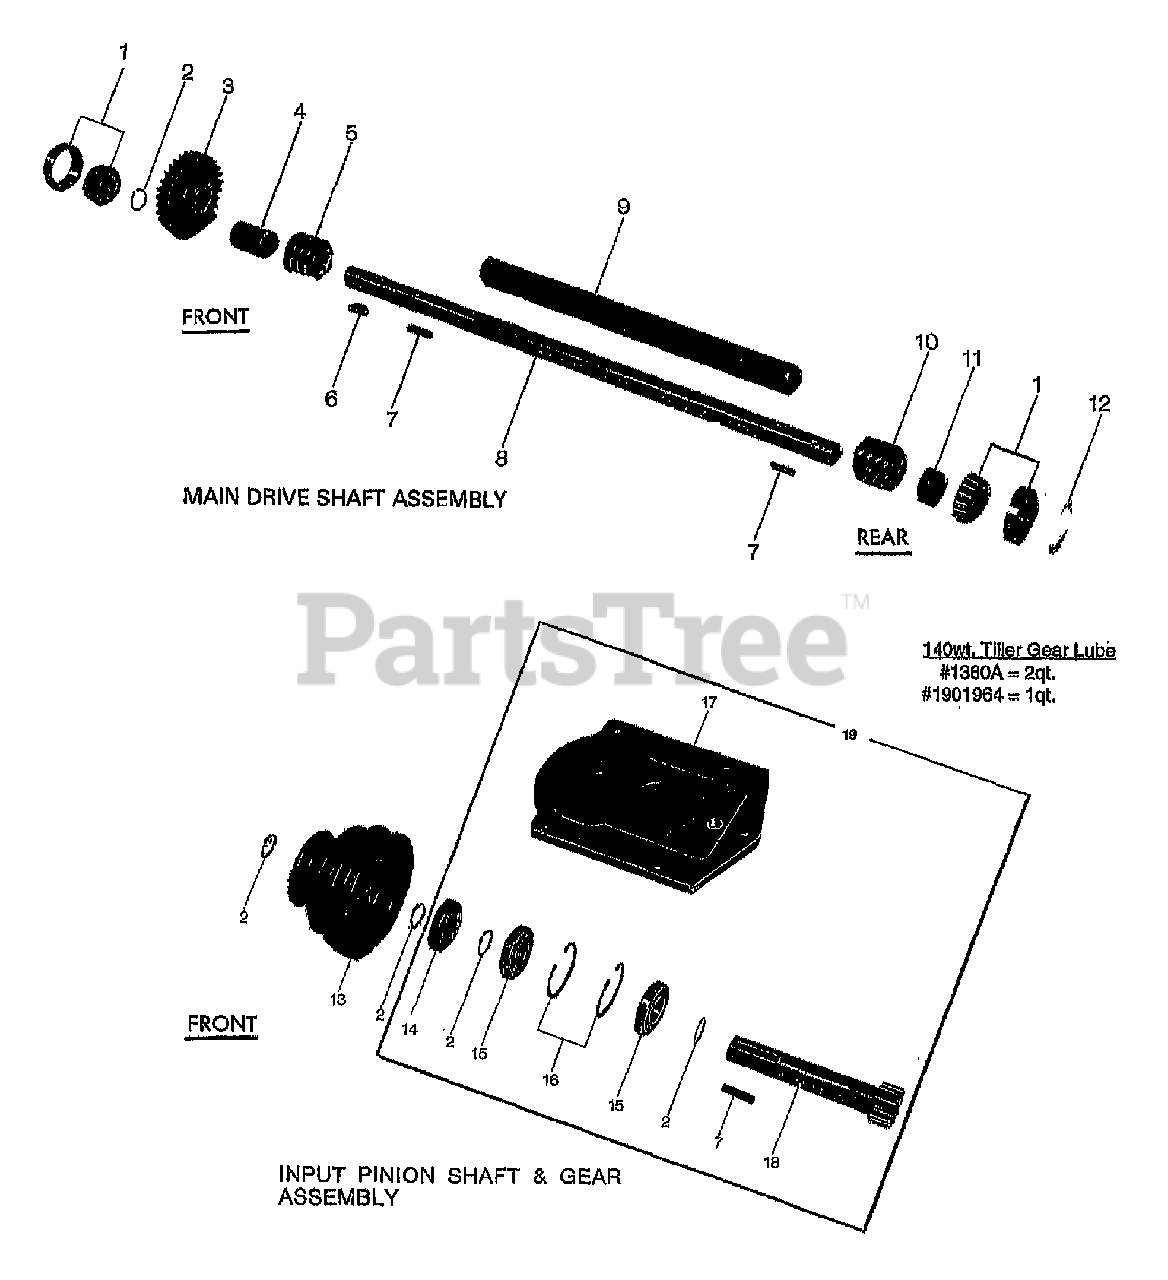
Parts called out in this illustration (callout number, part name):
1	KIT-BRG CONE&RACE-DRIVESHAFT
2	RING-RETAIN EXT .707 ID
3	GEAR-SPUR 30 TEETH
4	SPACER-1X.76X1.25
5	WORM-1.25 PD .314 LEAD
6	KEY-WOODRUFF #607
7	KEY-.188 SQX1.0
8	SHAFT-DRIVE MACH
9	TUBING-MACH
10	WORM-1.25 PD 1.88 LEAD
11	SPACER-1X.76X.54
12	SHIM-REAR BEARING CAP - 1.75X1.5X.01
12	SHIM-REAR BEARING CAP -1.75X1.5X.03
12	SHIM-REAR BEARING CAP -1.75X1.5X.005
13	PULLEY-DRIVE MACH
14	SEAL-OIL .75 ID (FORMERLY #611)
15	BRG-BALL (10 BALLS)(FORMERLY #436)
16	RING-RETAINING (SNAP RING, INTERNAL) ( FORMERLY #514)
17	OBS-COVER-TRANS W/BRG CUP(INCL. #1 PART #1714)
18	GEAR-SPLINE 10 TEETH MACH
19	COVER-TRANS W/BRG CONE, INCL. 2, 14-18
